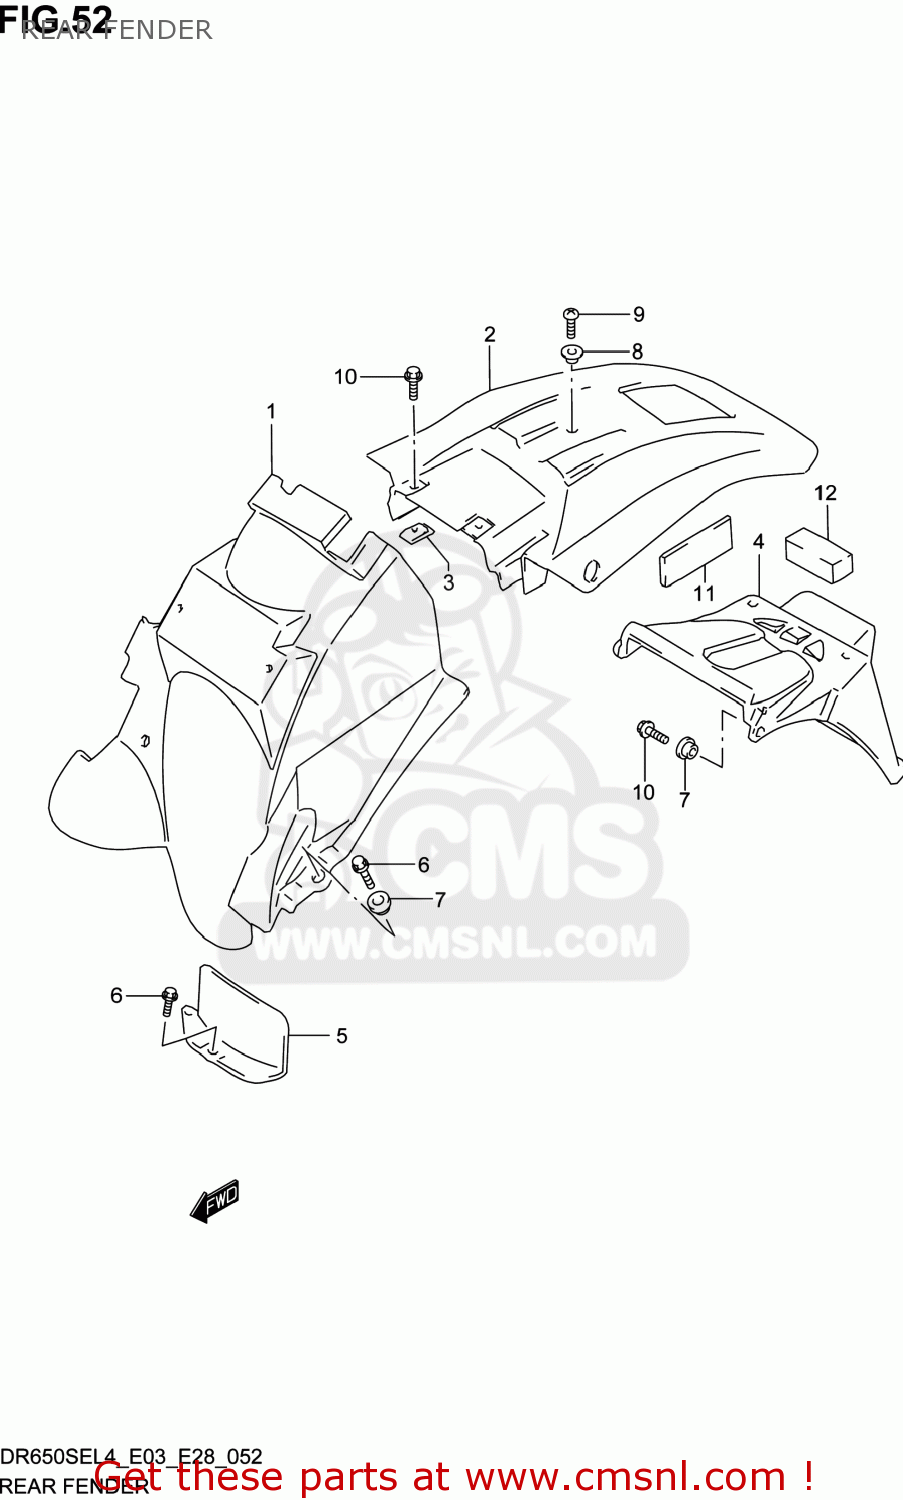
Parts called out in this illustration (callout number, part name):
1	BODY,RR FENDER FR
2	BODY,RR FENDER
3	PLATE,FRAME COVER
4	EXTENSION,RR FENDER
5	MUDGUARD,RR FENDER
6	BOLT(6X16)
7	WASHER
8	WASHER
9	SCREW(6X16)
10	BOLT
11	CUSHION,RR FENDER
12	CUSHION
